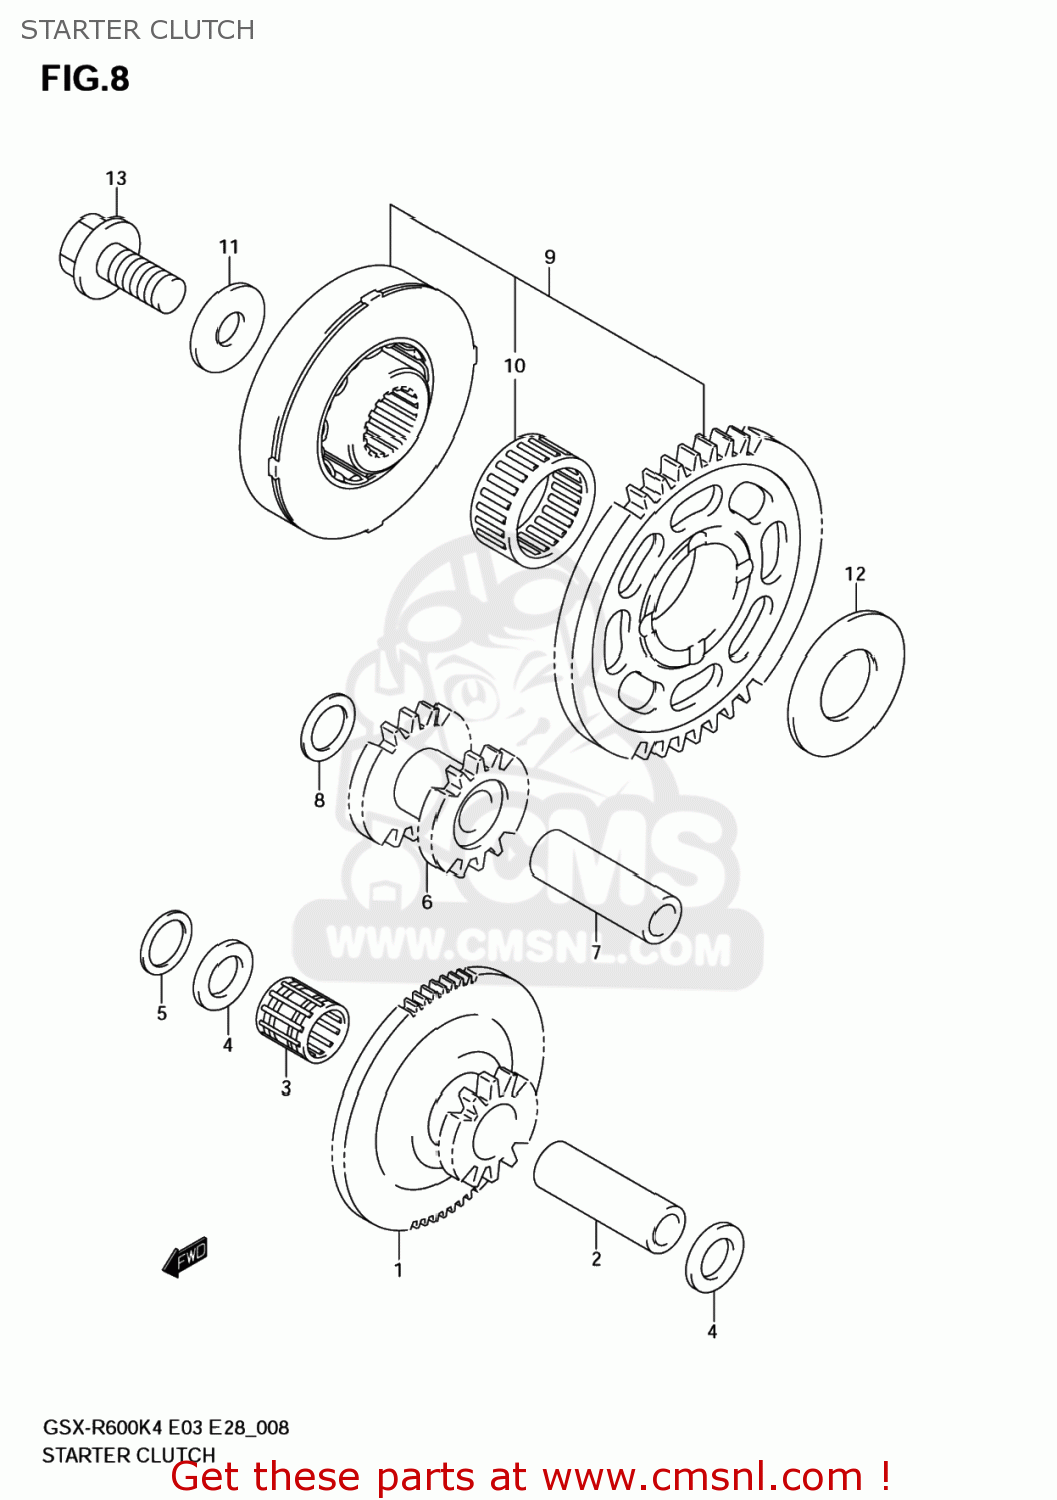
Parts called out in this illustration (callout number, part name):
1	GEAR,STARTER IDLE NO.1
2	PIN,PISTON
3	BEARING(12X16X16)
4	SHIM(12X20X1)
5	WASHER
6	GEAR,STARTER IDLE NO.2
7	PIN,PISTON
8	WASHER
9	CLUTCH SET,STA
10	BEARING(26X31X16)
11	WASHER
12	WASHER
13	BOLT(10X23)
